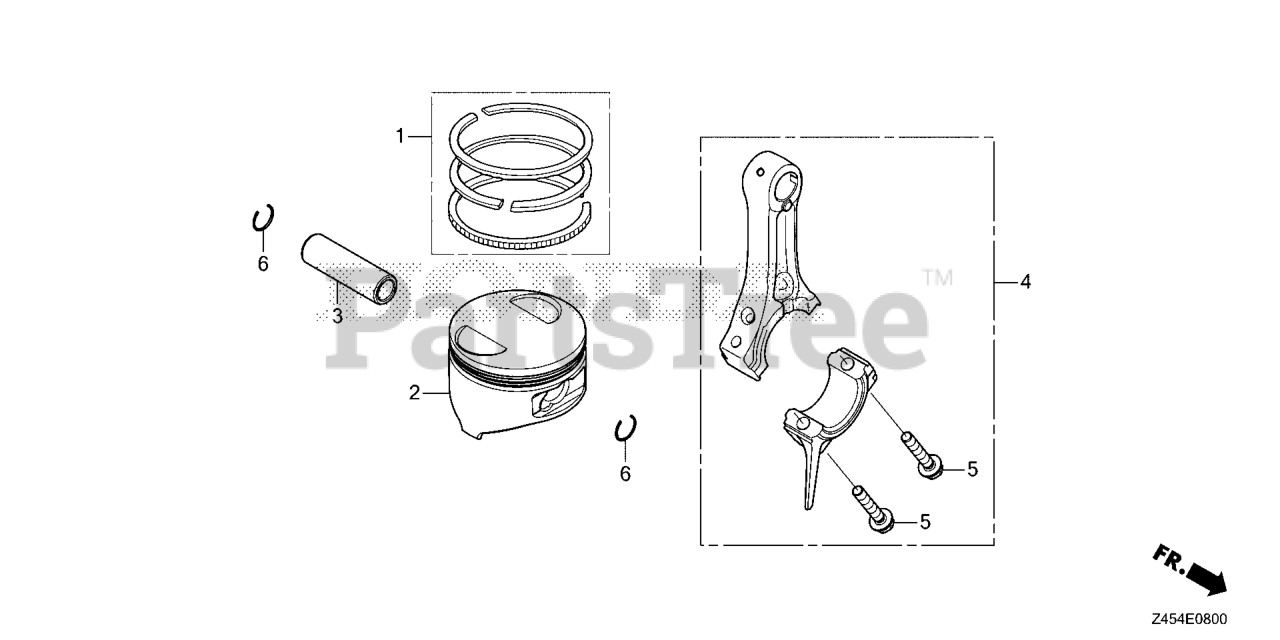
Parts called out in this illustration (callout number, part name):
1	RING SET, PISTON
3	PIN, PISTON
4	CONN ROD ASSY.
5	BOLT, CONNECTING ROD (6X32)
6	CLIP, PISTON PIN (13MM)
